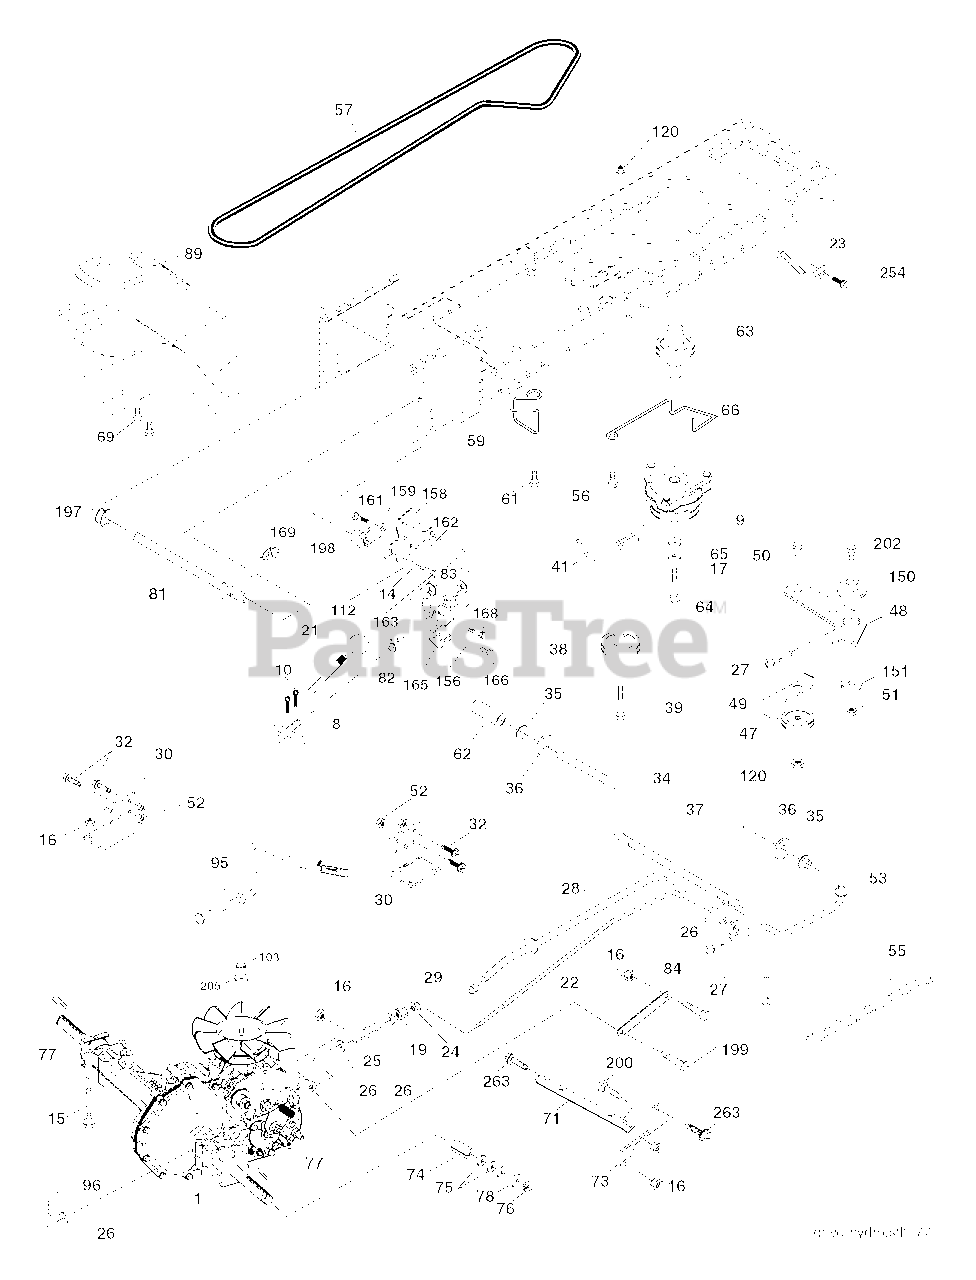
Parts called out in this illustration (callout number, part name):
9	Clutch Ogura
10	Pin Cotter 1/8 x 1 CAD
14	Washer Lock Hvy Helical
15	Bolt, Hex FLGHD 5/16-18 Gr. 5
16	Nut Lock Hex W/Ins 5/16-18 unc
19	Nut Lock Hex W/Wsh 3/8-16 unc
22	Rod, Brake Hydro
23	Bracket Anti Rotation
24	Nut
25	Spring, Brake Rod
26	Washer
27	Pin Cotter 1/8 x 3/4 CAD.
28	Rod, Parking Brake
29	Cap, Parking Brake
30	Bracket, Transaxle
32	Bolt Hex Hd 5/16-18 unc x 3/4
34	Shaft, Foot Pedal
35	Bearing, Nylon
37	Pin, Roll
38	Pulley, Composite
39	Bolt Rdhd 3/8-16 unc x 2-3/4 Gr. 5
41	Keeper, Belt Idler
47	Pulley, Idler, V-Groove
48	Bellcrank Clutch Grnd Drv STL
49	Retainer, Belt
50	Bolt Carr Sh 3/8-16 x 1-1/2 Gr. 5
51	Nut Crownlock 3/8-16 unc
52	Nut Crownlock 5/16-18 unc
53	Link, Clutch
55	Spring, Return, Clutch
56	Screw 3/8-16 x 1-1/4
57	V-Belt, Ground Drive
59	Keeper, Center Span
61	Screw 3/8-16 x .875
62	Cover, Pedal
63	Pulley, Engine
64	Bolt Hex 7/16-20 x 4 x Gr. 5-1.5 Thr
65	Washer
66	Keeper Belt Engine
69	Screw Hex Wsh Hi-Lo 1/4 x 1/2 unc
71	Strap Torque Lh Hydro
73	Strap Torque Rh Hydro
74	Spacer, Axle
75	Washer 25/32 x 1-1/4 x 16 Ga.
77	Key, Square
78	Washer 25/32 x 1-5/8 x 16 Ga.
81	Shaft Asm. Cross Hydro
82	Spring Torsion T/A
83	Washer 17/32 x 3/4 x 16 Ga.
84	Link Transaxle
89	Console, Shift
95	Control Asm Bypass Hydro
96	Retainer Spring 1" Zinc/Cad
103	Nut Hex Jam Toplock 1/2-20 unf
112	Washer 9/32 x 3/4 x 10 Ga.
120	Nut Lock Flg 3/8-16 unc
150	Spacer Retainer
151	Washer 13/32 x 2 x 10 Ga.
156	Washer Srrted 5/16 ID x 1.125
158	Bracket Shift Mount
159	Hub Shift
161	Bolt Rdhd Sqnk 1/4-20 x 3/4 Gr. 5
162	Nut Crownlock 1/4-20 unc
163	Bolt Hex Fin 1/4-20 unc x 1 Gr. 5
165	Bracket Pivot Lever
166	Screw 5/16-18 x 5/8
168	Bolt Shoulder 5/16-18 x .561
169	Plate Fastening Lt
197	Nyliner Snap-In 5/8" ID
198	Washer Nyl 7/8 ID x .105
199	Bolt Shoulder 5/16-18 unc
200	Bolt Rdhd Sqnk 5/16-18 unc x 1
202	Bolt Carr Sh 3/8-16 x 1-1/2 Gr. 5
205	Washer 17/32 x 1 x 16 Ga.
254	Screw 3/8-16 x 1
263	Thdrol Screw 3/8-16 x 3/4
